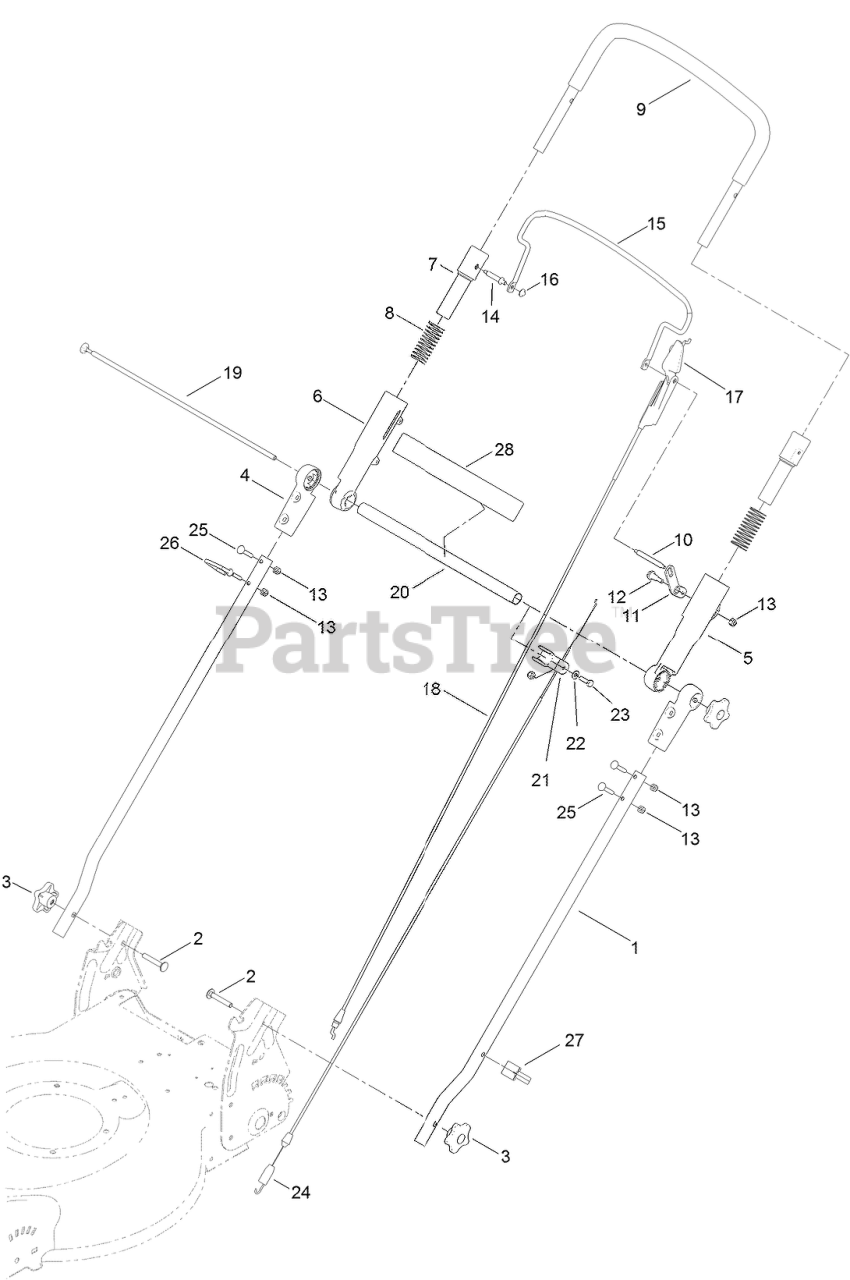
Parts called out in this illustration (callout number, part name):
1	HANDLE-LOWER
2	Screw-CARR
3	KNOB-HANDLE
4	MOUNT-HANDLE, LOWER
5	SLEEVE-OUTER, LH
6	SLEEVE-OUTER, RH
7	SLEEVE-INNER
8	SPRING-COMPRESSION
9	UPPER HANDLE ASM
10	PIN-BAIL, LH
11	LEVER-TRACTION
12	BOLT-SHOULDER
13	NUT-LOCK, NI
14	PIN-HANDLE
15	BAIL-BRAKE
16	RETAINER-PUSH ON
17	STOP-PIVOT
18	CABLE-BRAKE
19	ROD-THREADED
20	TUBE-CROSS
21	CLAMP-CABLE
22	WASHER-FLAT
23	SCREW-HH
24	CABLE-TRACTION
25	SCREW-CARR
26	GUIDE-ROPE, UPPER
27	GUIDE-CABLE
28	DECAL-ADS
